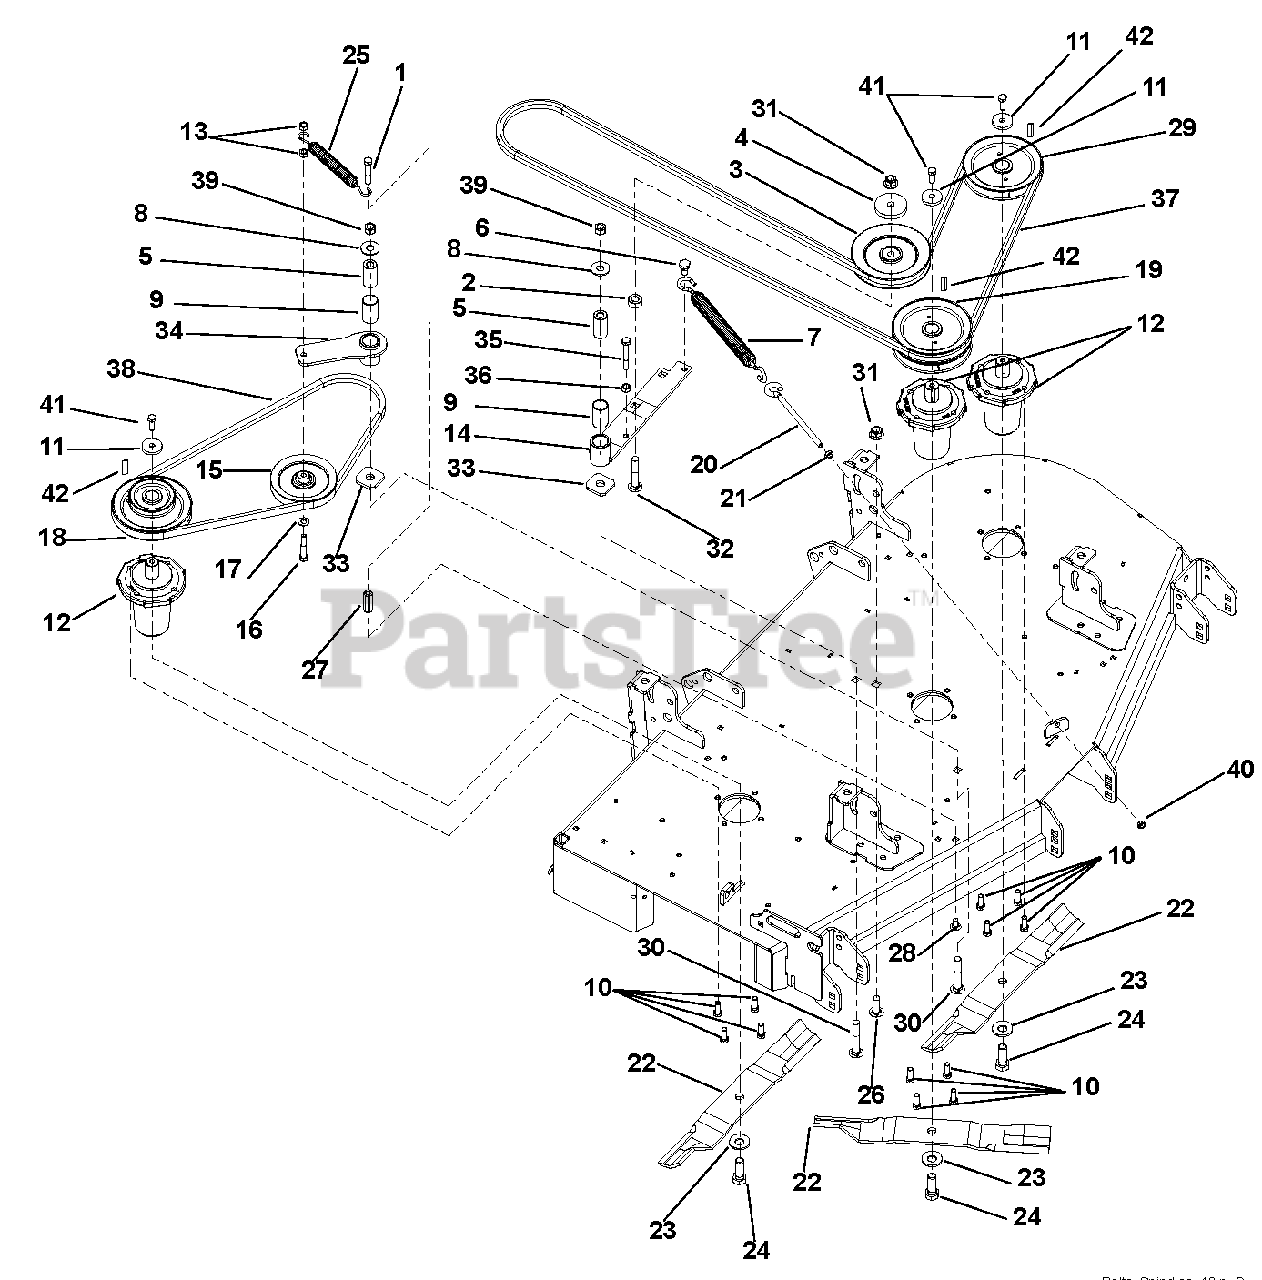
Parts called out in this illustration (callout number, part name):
1	Bolt, Hex .38-16 x 1.50
2	Bushing, Spacer .502 x .997 x .50
3	Sheave, .50" ID x 6.00" OD V-Idler
4	Cap, Idler Bearing Sealing
5	Bushing, Spacer .505/.500 x .999/.996 x 2.05/2.03
6	Bolt, Shoulder EP .38-16 x .30 Hex
7	Spring, Extension (Deck Idler)
8	Washer, Flat Steel .563 x 1.38 x .109
9	Bushing, 1.00 x 1.125 x 1.936
10	Bolt, Hex .38-16 x 1.00
11	Retainer, Sheave
12	Spindle Assembly
13	Nut, Locking Center .38-16
14	Weldment, Idler Arm
15	Sheave, .38" ID x 5.00" OD V-Idler
16	Bolt, Hex .38-16 x 2.25
17	Washer, Flat Steel .406 x .812 x .065
18	Pulley, Double, 1" ID x 5.75" & 3.50" OD (991079, 095, 102)
19	Pulley, Double, 1" ID x 5.75" OD (991079, 095, 102)
20	Bolt, .38-16 x 5.50 .62 Diameter Eye
21	Nut, Hex, Jam .375-16
22	Blade, 16.19" Mower (991079, 095, 102)
23	Washer, Bellville .63 x 1.625 x .14
24	Bolt, Hex .62-18 x 1.75 Grade 8 (Torque to 115 – 125 ft. lbs., 155 – 169 N-m)
25	Spring, Extension
26	Bolt, Round Head Square Neck .50-13 x 1.5, Full Thread
27	Nut, Coupling .375-16 x 1.75
28	Bolt, Round Head Square Neck .38-16 x 1.00
29	Pulley, V, 1" ID x 5.75" OD (991079, 095, 102)
30	Bolt, Round Head Square Neck .50-13 x 3.25 G5YZ
31	Nut, .50-13 Nyloc Flange
32	Bolt, Round Head Square Neck .50-13 x 3.00
33	Washer, Flat .640 x 1.75 x .250
34	Weldment, Idler Arm
35	Bolt, Hex .38-16 x 2.75
36	Nut, Hex .38-16
37	Belt, BB 118.00 Wrapped Hex (991079, 095, 102)
38	Belt, B 51.18 Raw Cogged (991079, 095, 102)
39	Nut, Locking Center .50-13
40	Nut, Lock Center Jam .375-16
41	Bolt, Hex .38-16 x 2.75 Grade 8
42	Key, Square .25 x .25 x 1.00
